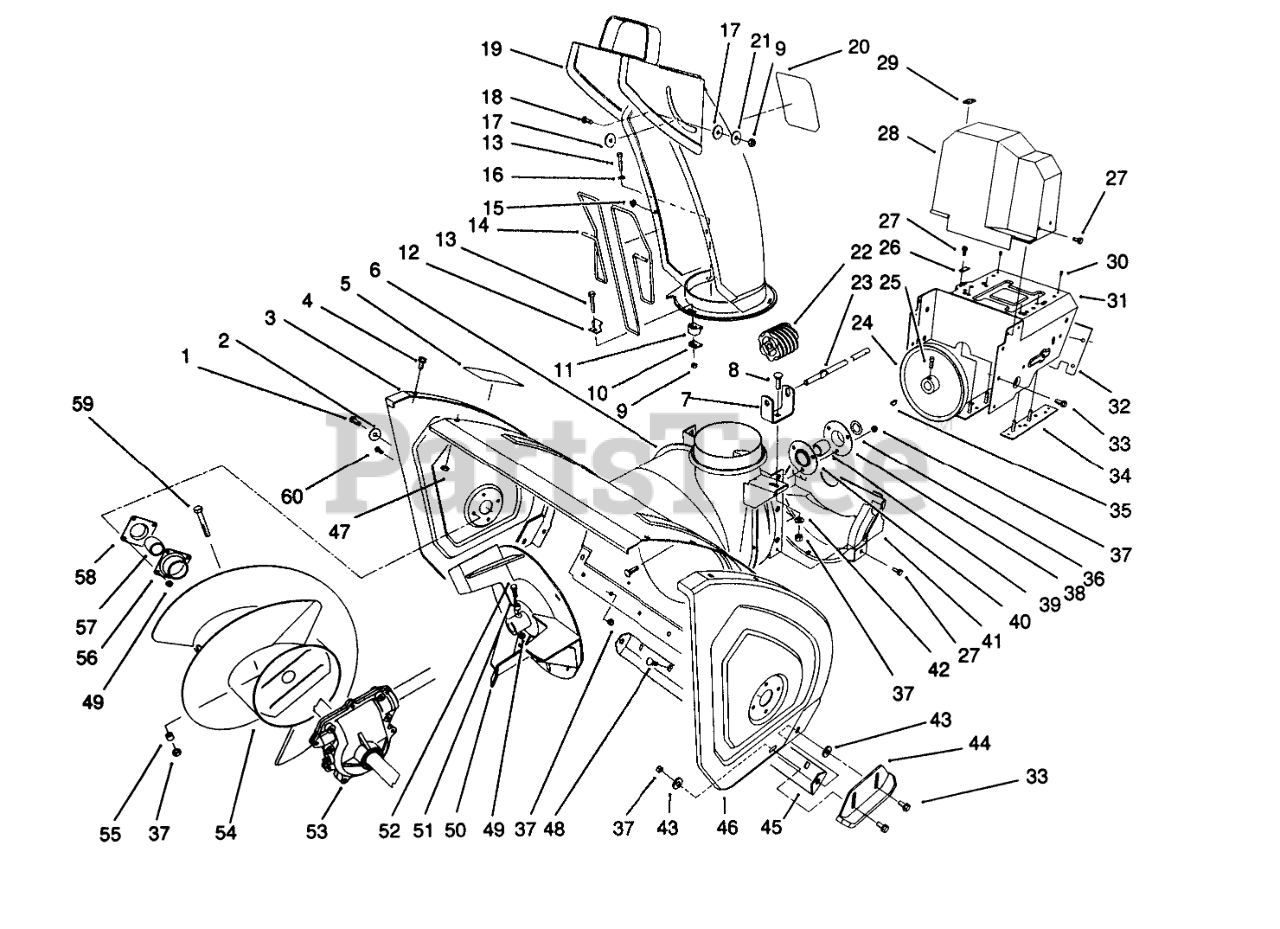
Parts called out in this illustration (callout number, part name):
1	SCREW-HH
2	WASHER
3	Plate-Side
4	SCREW-HHF
5	DECAL-WARNING, AUGER
6	Housing-28"
7	BRACKET-WORM, CHUTE
8	BOLT-CARR
9	NUT-LOCK, NI
10	PLATE-RETAINER, CHUTE
11	RETAINER-CHUTE
12	CLIP-GUARD, CHUTE
13	SCREW-HSH
14	GUARD-CHUTE
15	NUT-PUSH
16	WASHER-FLAT
17	WASHER-PLASTIC
19	Assembly
20	Decal-Danger
21	WASHER-FLAT
22	GEAR-WORM
23	ROD-CHUTE, LOWER
24	PULLEY-IMPELLER
25	SCREW-SET, SQH
26	RETAINER-CABLE
27	SCREW-HWH
28	COVER-BELT, UPPER
29	COVER-CABLE
30	RIVET-POP
31	Frame-Engine
32	Cover-Frame, Engine
33	SCREW-HHF
34	PLATE ASM FRM LH 11 B&S
35	KEY-WOODRUFF
36	WASHER-THRUST
37	NUT-LOCK, NI
38	Flange-Bearing (Rear)
39	BEARING-BALL
40	Flange-Bearing (Front)
41	Cover-Belt (Lower)
42	WASHER-PLAIN
43	WASHER
44	Skid
45	Blade-Scraper
46	Plate-Side
47	NUT-LOCK, NI
48	SCREW-CARR
49	NUT-LOCK, NI
50	Impeller
51	SPACER
52	SCREW-HHF
53	LH AUGER GEARCASE ASM
54	Auger-R.H.
55	SPACER-HUB, AUGER
56	BEARING-FLANGE, FRONT
57	BEARING
58	BEARING-FLANGE, REAR
59	Auger Bolt
60	SCREW-HH
